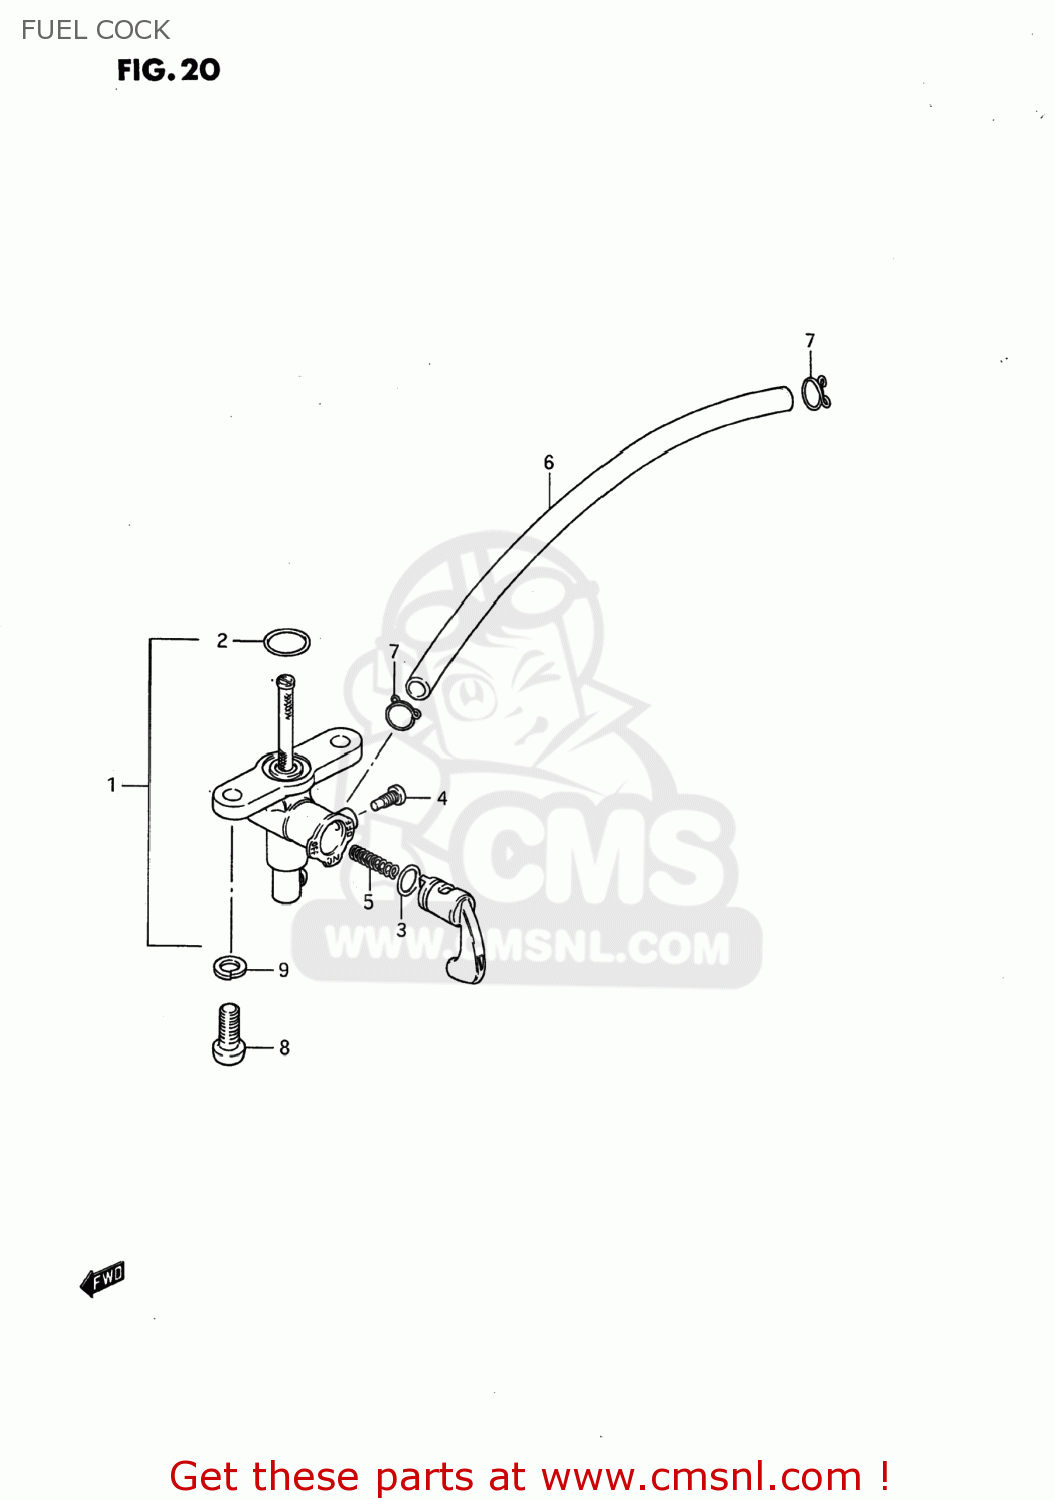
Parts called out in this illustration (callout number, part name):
1	COCK ASSY,FUEL
2	O RING
3	O RING,LEVER
4	SCREW
5	SPRING,FUEL COCK VALUE
6	HOSE(5X8.2X600)
7	CLIP
8	SCREW
9	WASHER,LOCK
